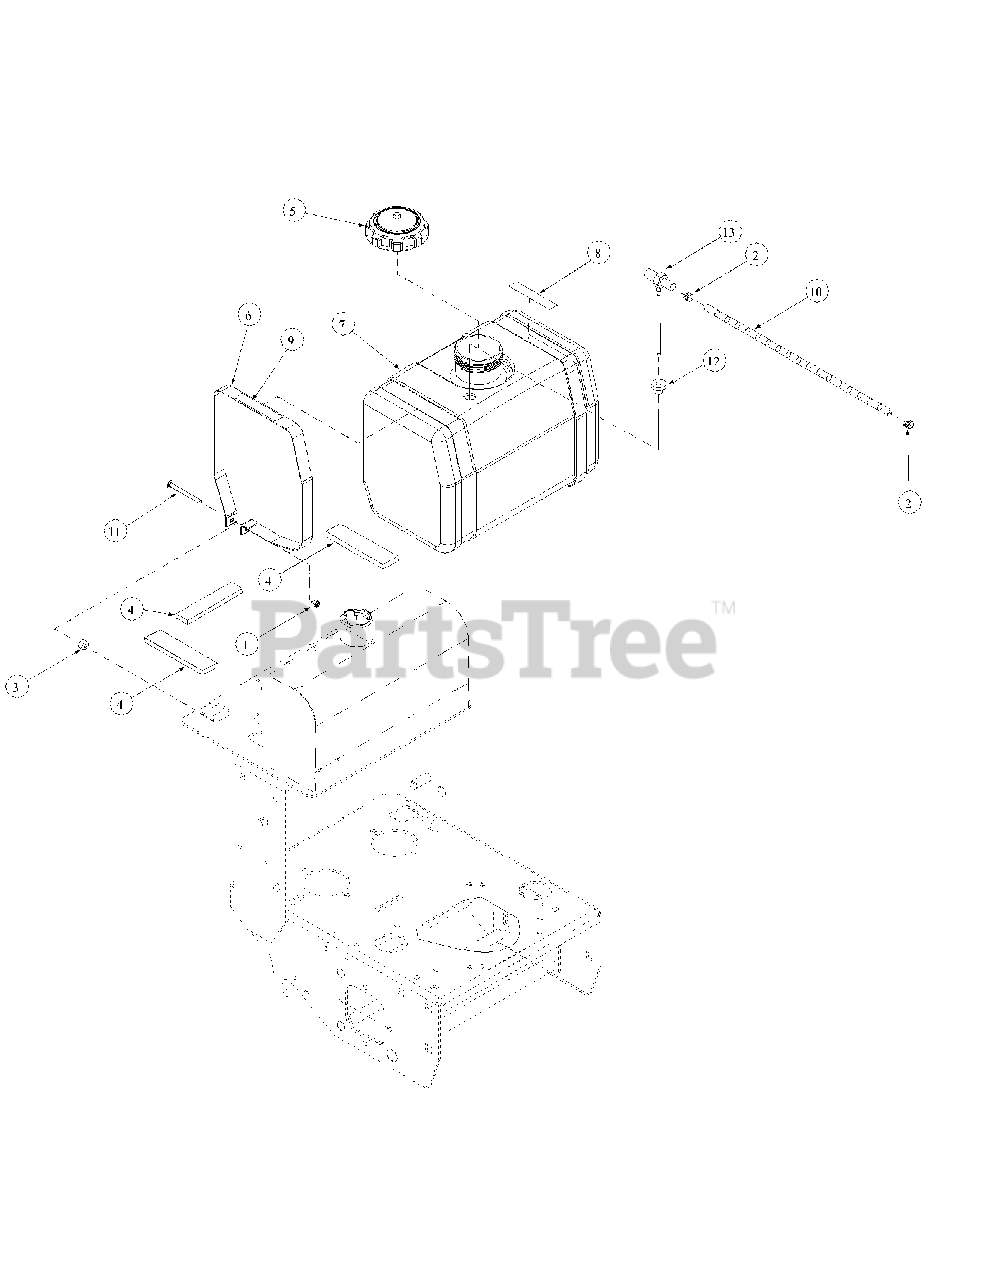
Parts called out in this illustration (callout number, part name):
1	Lock Nut, Nylon Insert, 1/4-20
2	Uni-Clamp
4	Stop Pad, Rubber
5	Fuel Cap, 3.5
6	Fuel Tank Strap
7	Fuel Tank
8	Mower Warning Label, Turn off Engine
9	Mower Instruction Label, Fuel Valve
10	Fuel Hose, 18"
11	Carriage Bolt, 1/4-20 x 3.00
12	Grommet Fuel Tank
13	Shutoff Valve
